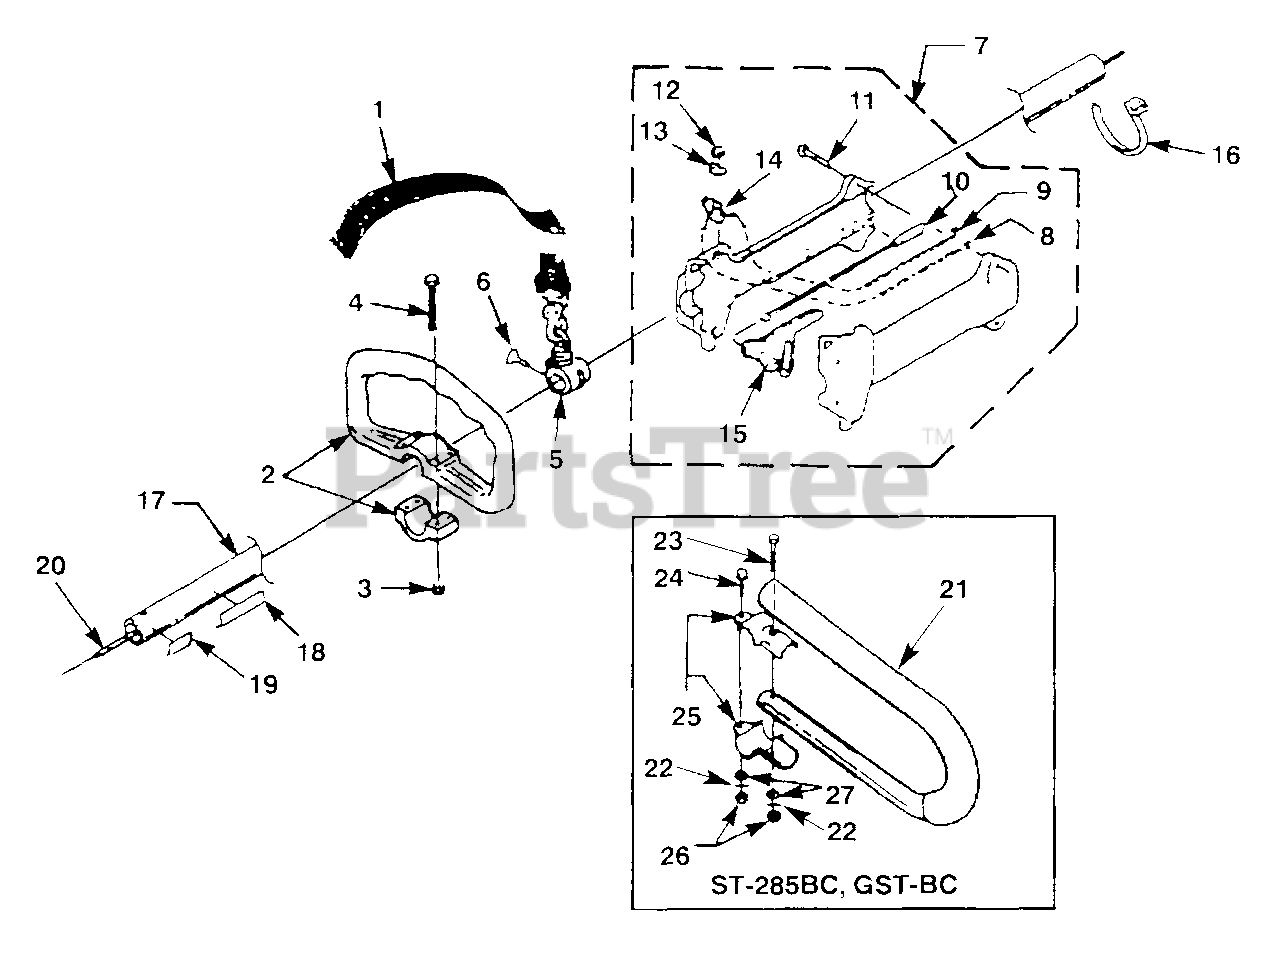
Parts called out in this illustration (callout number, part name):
1	HARNESS w/Connector
2	HANDLE KIT - Front
3	NUT - Hex (M5 X 0.8)
4	SCREW - Hex Hd (M5 X 0.8 X 35)
5	BRACKET - Hanger
6	SCREW - Thumb (10-24 X 1/2")
7	HANDLE GRIP ASSEMBLY
8	LEAD - Ground
9	LEAD - Electrical
10	THROTTLE CABLE
11	SCREW - Plastite (8 X 3/4")
12	NUT - Hex Lock
13	PLATE - Indicating
14	SWITCH - Toggle
15	TRIGGER
16	CABLE TIE
17	HOUSING - Drive Shaft
18	DECAL - Starting Instructions
19	DECAL - Safety
19	DECAL - Warning
20	DRIVE SHAFT
20	SHAFT - Flexible
21	J-HANDLE BAR KIT
22	Washer - Lock
23	SCREW - Hex Hd (1/4-20 X 1/2")
24	SCREW - Hex Hd (1/4-20 X 1")
25	CLAMP - Handle Bar
26	NUT - Hex (1/4-20)
27	WASHER - Flat
